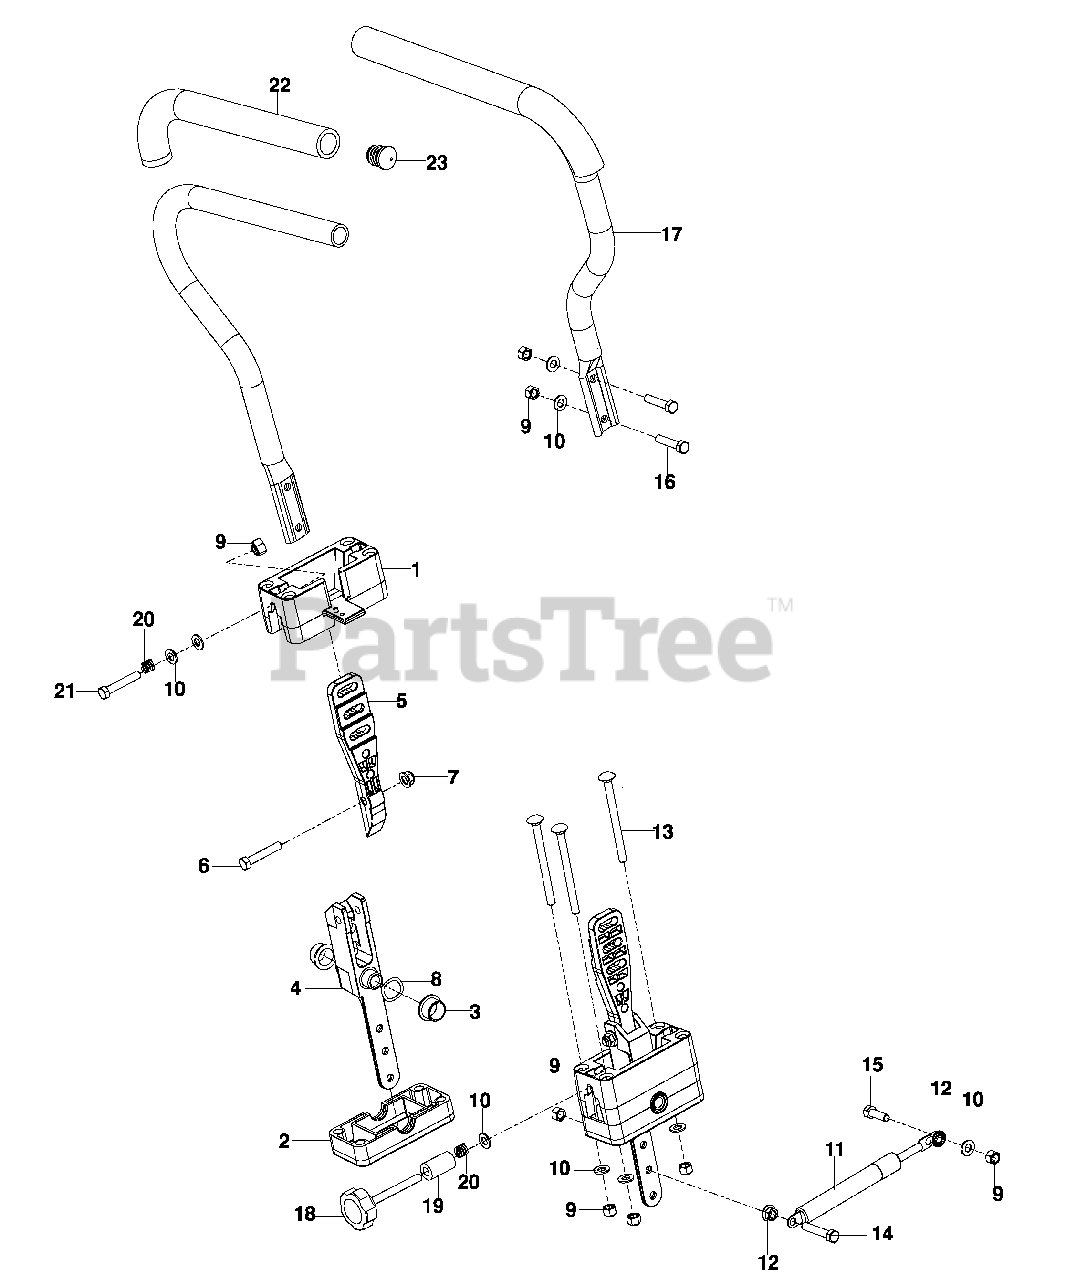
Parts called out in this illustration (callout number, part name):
1	BLOCK, UPPER
2	BLOCK, LOWER
3	BEARING, FLANGE
4	PIVOT SECTION, DRIVE
5	MOUNT, DRIVE CONTROL
6	HCS 5/16-18 x 1¾
7	NUT 5/16-18 FLANGE NYLOC
8	WASHER, .825 x 1.087 WAVE
9	NUT 5/16-18 HEX NYLOC
10	WASHER 5/16 SAE FLAT
12	NUT 5/16-18 HEX WHIZLK
13	RHSNB 5/16-18 x 4
14	HCS 5/16-18 x 1¾ TPBLT
15	HCS 5/16-18 x 1
16	HCS 5/16-18 x 1½
17	LEVER, w/GRIP
21	HCS 5/16-18 x 2 TPBLT
22	GRIP, FOAM
